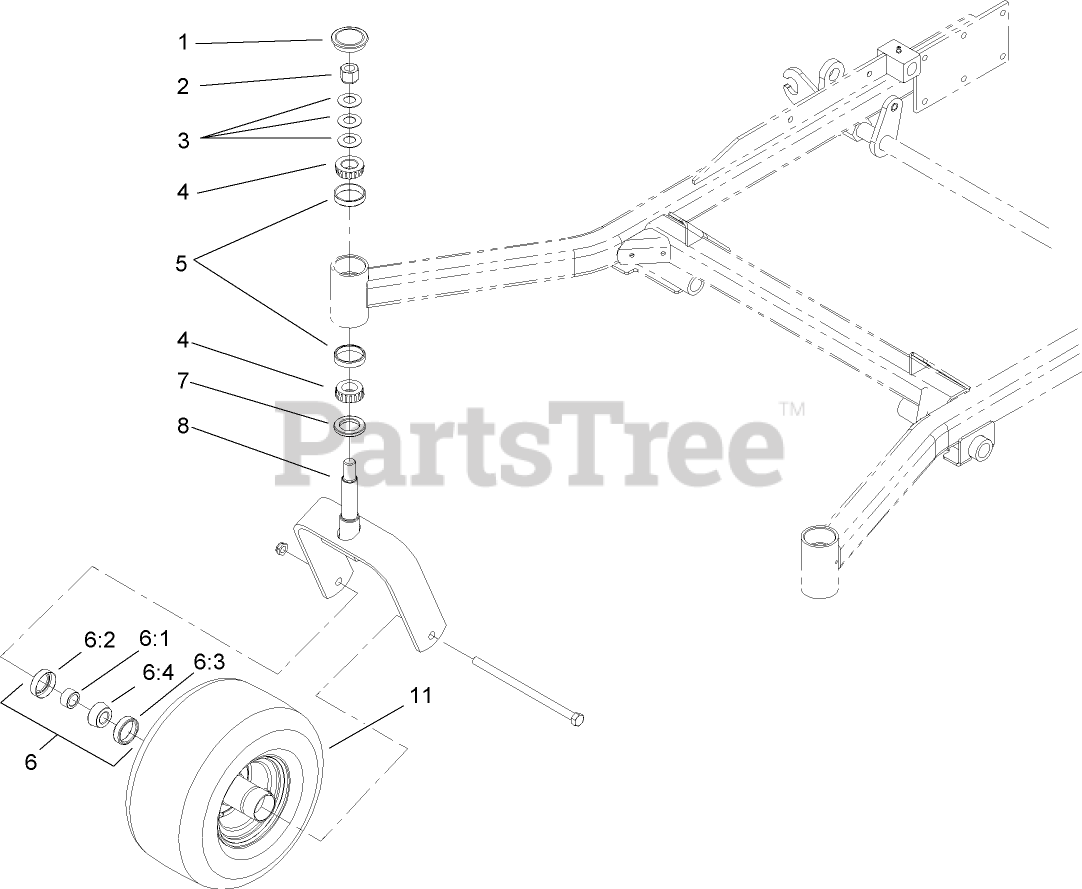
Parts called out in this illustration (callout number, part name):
1	CAP-GREASE
2	NUT-LOCK, NI
3	WASHER-BELLVILLE
4	BEARING-CONE, TAPERED
5	BEARING-CUP, TAPERED
6	CASTER WHEEL BEARING KIT
6:1	SPACER-BEARING
6:2	SEAL-BEARING
6:3	BEARING-CUP
6:4	BEARING-CONE, TAPER
7	SEAL-GREASE
8	CASTER
11	CASTOR WHEEL ASM
